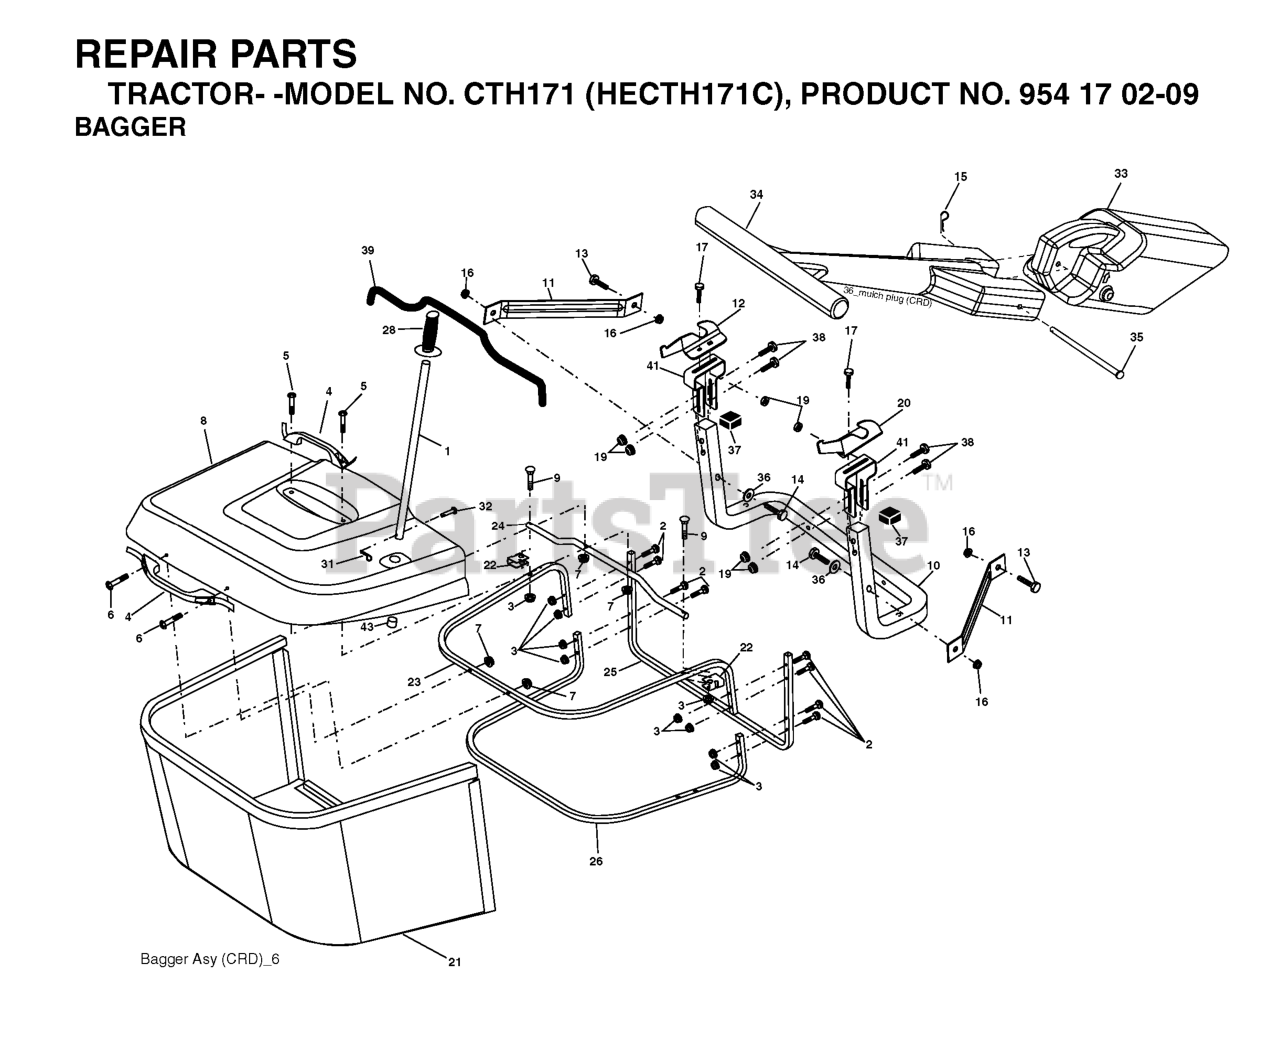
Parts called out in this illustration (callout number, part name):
1	TUBE HANDLE
2	Bolt Carriage 1/4-20 x 2.0 Gr.5
3	NUT T
4	HANDLE.BAGGER.W/LVRS.BLK.CRD
5	SCREW.PAN.HEAD
6	REPL BY 532 75 00-29
8	COVER.PNT.BGR.CRD.WSLOTS.MS668
9	Bolt Carriage 1/4-20 x 2.25d x Gr.5
10	TUBE
11	BRACKET.SUPPORT.UPPER.BAG.CRD
12	BRKT PIVOT
13	BOLT
14	BOLT-HEX EAK
15	RETAINER-SPRNG RB
16	NUT LOCK FLG 3/8-16 UNC
17	RP BOLT 5/16-18 X3/4 ZN/YEL GR
19	NUT LOCK HEX FLANGE 5/16-18
20	BRKT.PIVOT.RH.CRD
21	GRASS BAG
22	BRKT.SIDE.BAG.CRD
23	TUBE.UPPER.BAG.CRD
24	TUBE.PIVOT.BAG.CRD.BLACK
26	TUBE.LOWER.BAG.CRD
28	GRIP.HANDLE.BLACK
31	RETAINER CLIP
32	RIVET,DRILLED
33	PLUG.MULCHER.92 CRD
34	HANDLE.MULCHER.92.CRD (2 2)
36	WASHER
37	Plug Support Bagger CRD
38	BOLT.5/16-18X2.5
39	SEAL.TRIM.37'
41	BRKT.VERT.ADJ.BAGGER.CRD
43	PLUG, TUBING END
